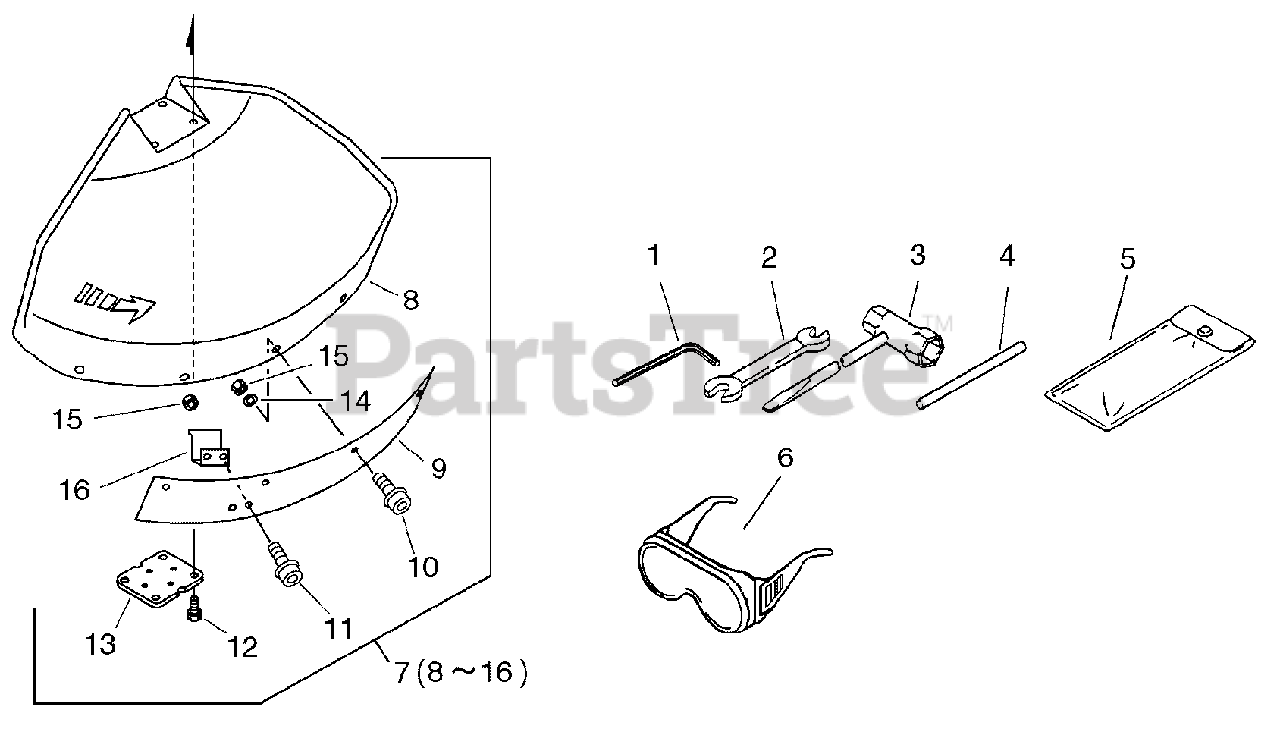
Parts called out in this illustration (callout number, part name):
1	WRENCH, ALLEN 4 MM
2	SPANNER 8×10
3	T-WRENCH 17x-19 L200
4	TOOL, LOCKING 5×120 MM
5	BAG, TOOL
6	GLASSES, SAFETY
7	DEBRIS SHIELD ASSY
8	SHIELD, DEBRIS
9	EXTENSION, SHIELD
10	SCREW 5×18
11	BOLT 5×14
12	BOLT 5×25
13	PLATE, SHIELD
14	WASHER 5.5×12×0.8
15	NUT M5
16	CUTTER, LINE
